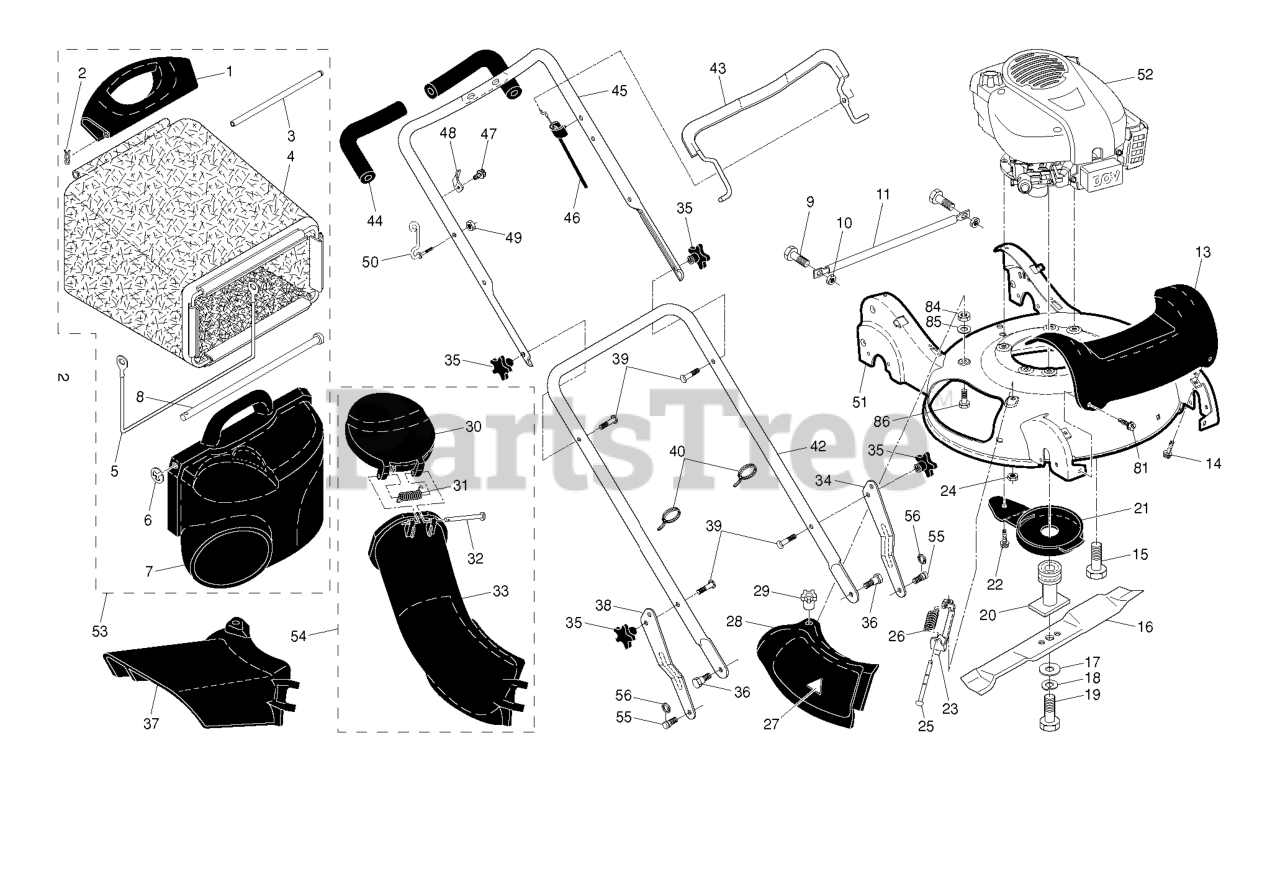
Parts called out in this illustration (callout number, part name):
1	HANDLE.GRASSBAG.REAR.H-GRAY
2	COTTER PIN (3 2)(2 2MC)
3	ROD.REAR.HANDLE.YELLOW
5	FRAME, GRASSBAG
7	DOOR, GRASSBAG
8	ROD, PIVOT
10	LOCKNUT.NYLOC.1/4-20
11	TUBE, REAR SKIRT
13	COVER.FRONT.21.HV.H-GRAY
14	SCREW, HEX WASHER HEAD
15	BOLT 3/8-16X1-1/8
16	Blade, 21"
17	WASHER,HARDEN
18	LOCKWASHER
19	BOLT.HD.HEAD.3/8-24X2.50 (2 2)
20	ADAPTER.BLADE
21	DEBRIS SHEILD
22	SCREW 1/4X20
23	BRACKET.ASM.HINGE
24	NUT.HEX.FLANGE.1/4
25	ROD.HINGE.1/4"3.82"
26	SPRING.MULCH.DOOR
27	DECAL.INTERNATIONL.CUTFINGER
28	MULCHER DOOR
29	KNOB.MULCH.DOOR
30	CHUTE.DOOR.21.HV.H-GRAY
32	ROD.HINGE.1/4"3.82"
33	DISCHARGE CHUTE PLASTIC
34	ADJUSTMENT BRACKET, LOWER LH
35	KNOB.HANDLE.PLASTIC.STAR.BLACK
36	SCREW.5/16X.680.TRIM.H
37	GUARD.CLIP.ON.21.HV.GRAY
38	BRACKET.ADJ.LOWER.HDL.RT.GREY
39	BOLT, HANDLE 5/16-18X1.75
40	TIE GUIDE
42	HANDLE.LOWER.GREY
43	BAIL.CONTROL.MZR.BS.ORANGE
44	GRIP.HANDLE.FOAM.WIDE.(1 SIDE)
45	HANDLE.ASM.UPPER.W/GRIP
46	CABLE.MZR.SNAP-IN
48	BRACKET.UPSTOP.RT
49	NUT
50	GUIDE.ROPE.WALK.MOWER
53	Grassbag Assembly, Complete
54	CHUTE.LOWER.ASM.WALK.MOWER
55	STUD.SHOULDER.T45.BZP
56	E-RING 7/16 RE
81	SCREW.HWH.13-16-5.8.BZP
84	NUT, HEX
85	LOCKWASHER
86	BOLT.CARRIAGE.1/4-20 X 7/8
